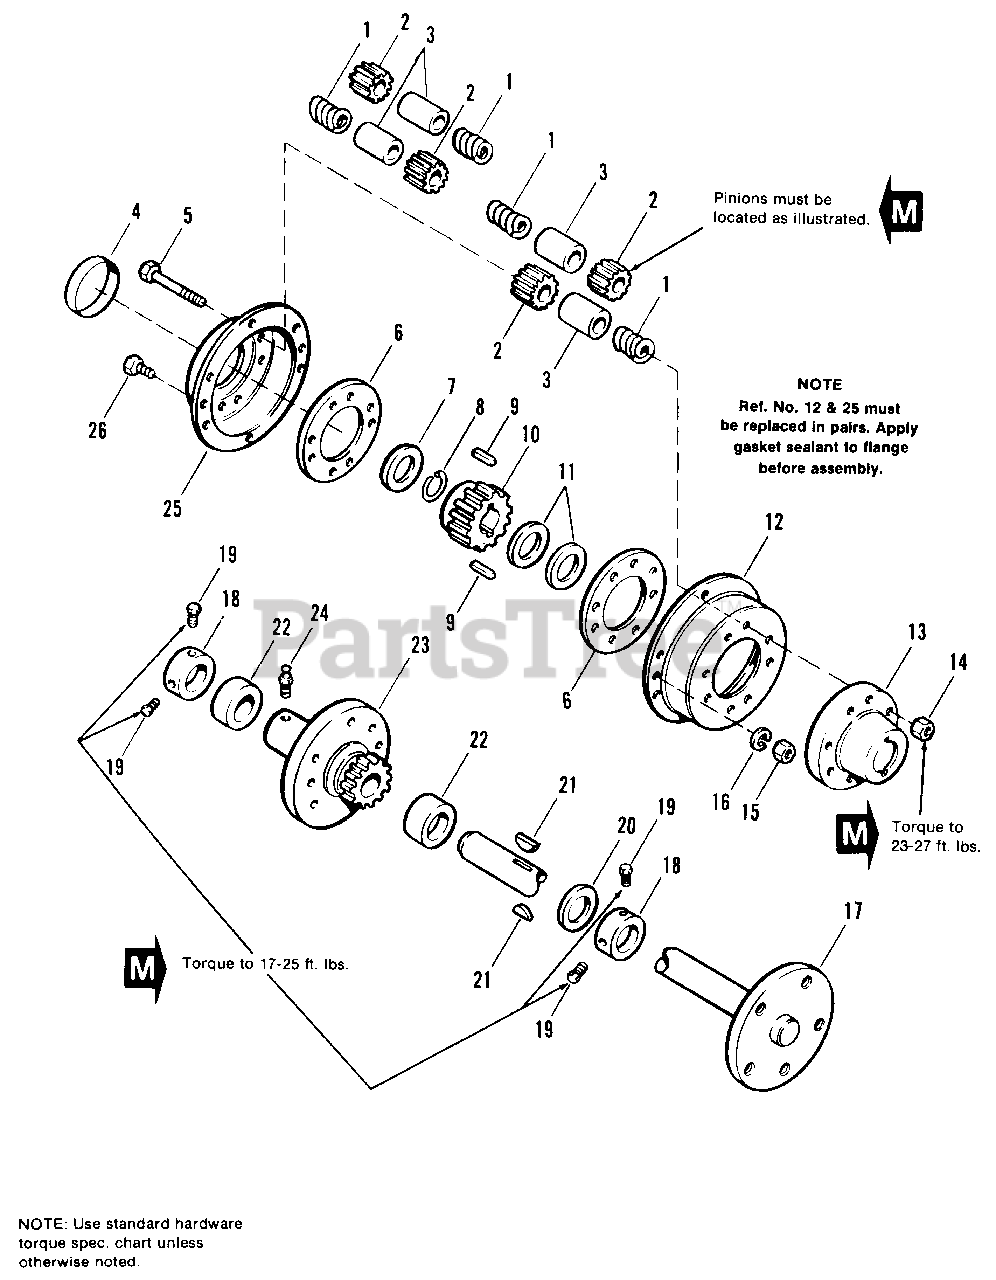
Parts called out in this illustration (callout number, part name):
1	SPRING
2	PINION, Differential
3	SPINDLE, Differential
4	SEAL, Cover
5	CAPSCREW, Hex Hd., 3/8-16 x 2-1/2
6	RlNG, Spacer
8	RING, Retaining
9	KEY, Hi-Pro
10	GEAR, Differential
12	COVER, Differential
13	CARRIER, Differential
14	LOCKNUT, Hex, 3/8-16
15	NUT, Hex, Full, 1/4-20
16	LOCKWASHER, 1/4
17	AXLE ASSY., Rear
18	COLLAR, Set
19	SETSCREW, 5/16-18 x 1/2
23	HUB ASSY., Wheel, RH
24	FITTING, Grease
25	COVER, Differential
26	CAPSCREW, Hex Hd., 1/4-20 x 5/8
26	DIFFERENTIAL SUBASSY. (See Note Below)
